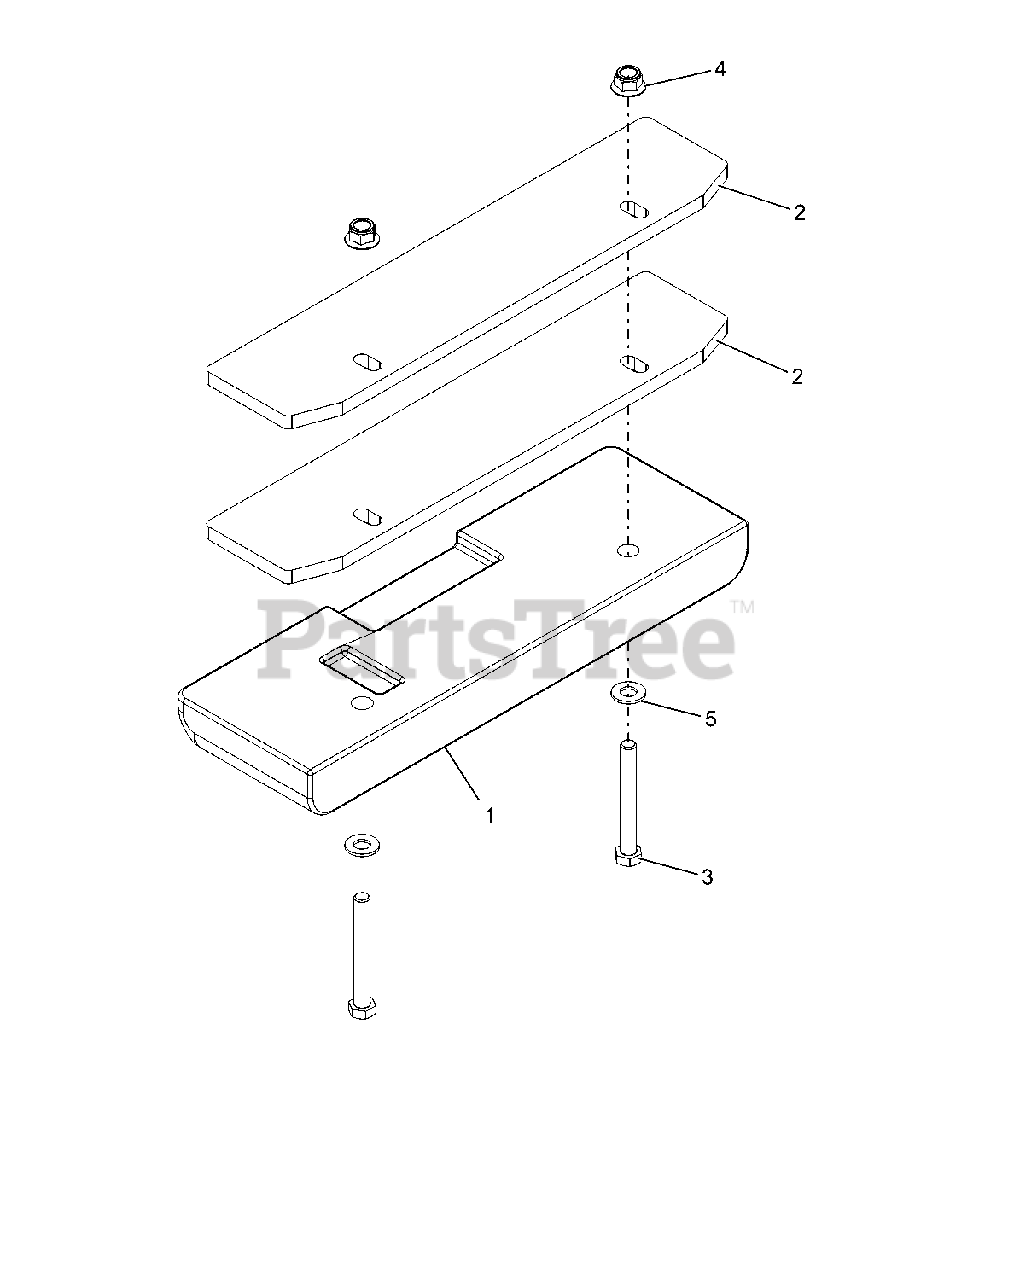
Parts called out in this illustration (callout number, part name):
1	WEIGHT, CAST IRON
2	PLATE, COUNTER WEIGHT
3	@BLT-HEX .50-13X4.00 GR5 YWZC
4	@NUT-LK-NYL-FLG .50-13 YWZC
5	@WSHR-FL-STL.531X1.06X.095YWZC
